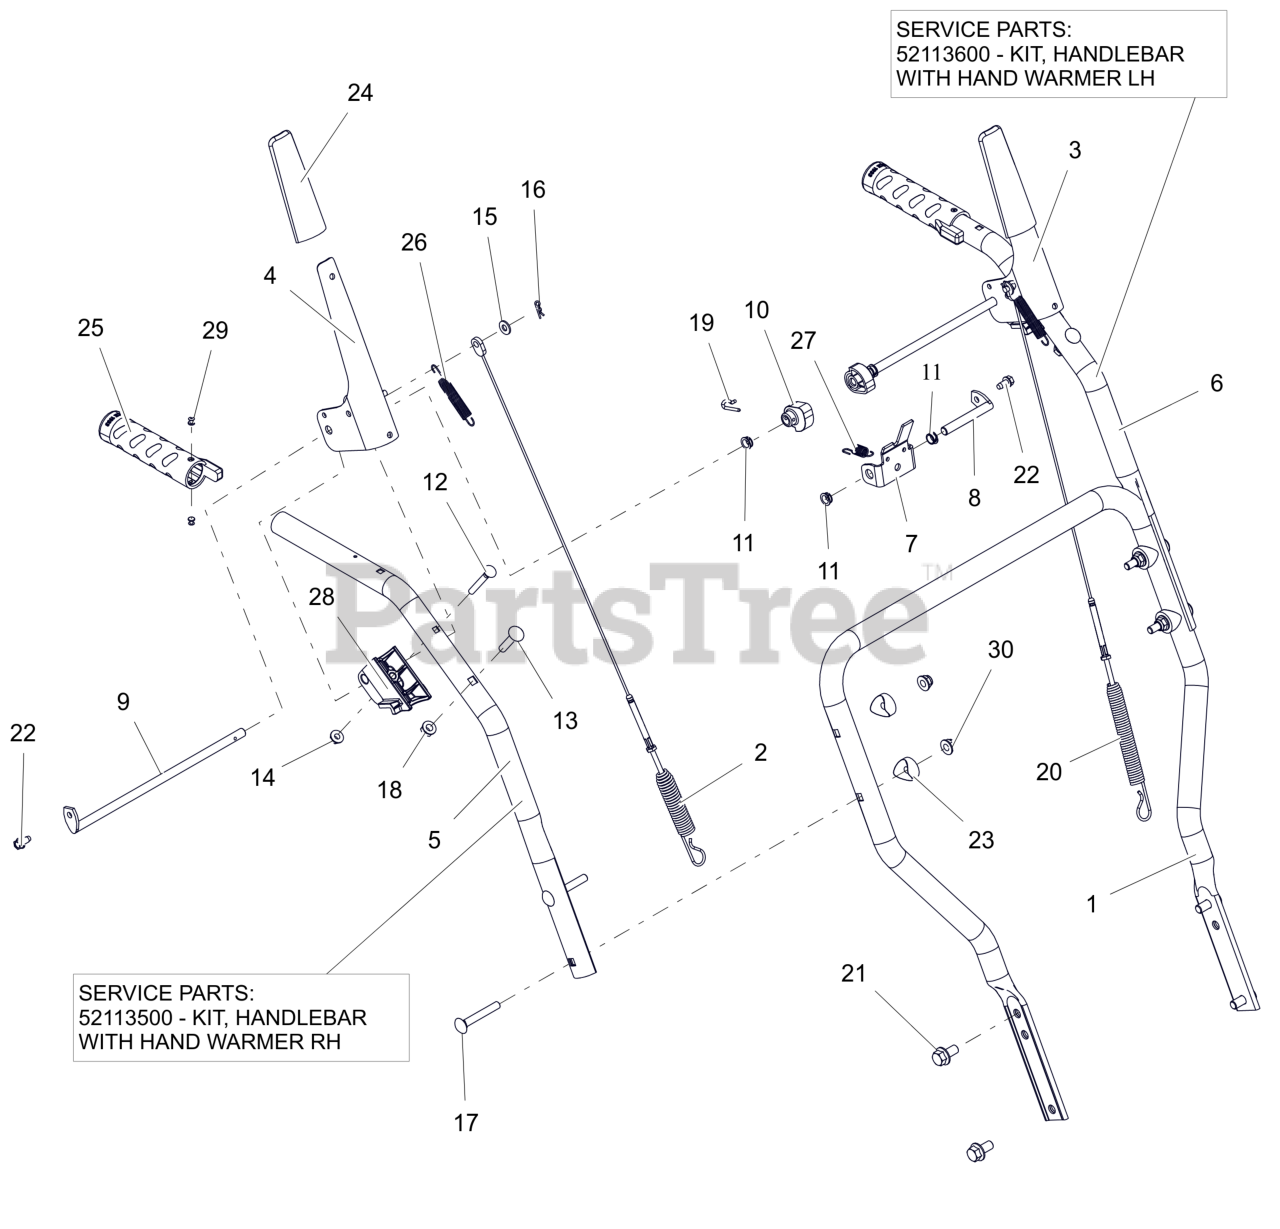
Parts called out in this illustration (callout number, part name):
1	HANDLEBAR- LOWER
2	CABLE, AUGER (DELUXE & PRO)
3	WLDMT, CLUTCH HANDLE - LH
4	WLDMT, CLUTCH HANDLE - RH
5	HANDLEBAR- UPPER - RH
5	KIT, HANDLEBAR WITH HAND WARMER RH
6	HANDLEBAR- UPPER - LH
6	KIT, HANDLEBAR WITH HAND WARMER LH
7	BRACKET, INTERLOCK ARM
8	ROD, PIVOT - INTERLOCK
9	ROD, PADDLE MOUNT - PRO
10	CAM, INTERLOCK
11	BUSHING, POLYLINER-.38 SNAPIN
12	BLT-RDHDXLSQNK .25-20X2.0 G5YZ
13	BLT,RHSN .31-18X1.50 G5 ZCC
14	NUT-LK-CTR-FLG .25-20 ZC120
15	WSHR,FLT .281X.625X.065 ZCC
16	PIN, HAIR #178 .06X.77 ZCC
17	BLT, RHSN .31-18X2.25 G5 ZCC
18	NUT-LK-TOP-FLG .312-18 GF ZCC
19	PIN, SPRING CLIP
20	CABLE, UPPER TRACTION
22	SCR-TAP .25-20X.50 HWH ZCC
23	SPACER, HANDLEBAR
24	COVER, PADDLE
25	GRIP- HEATED HANDLE - BLACK
26	SPRING, EXTENSION
27	SPRING-EXT .047X.438X1.45
28	BLOCK- CLUTCH PADDLE
29	RVT-POP #43 .125X.313 STL ZINC
30	NUT,LK-NYL-FLG .31-18 G5ZC120
